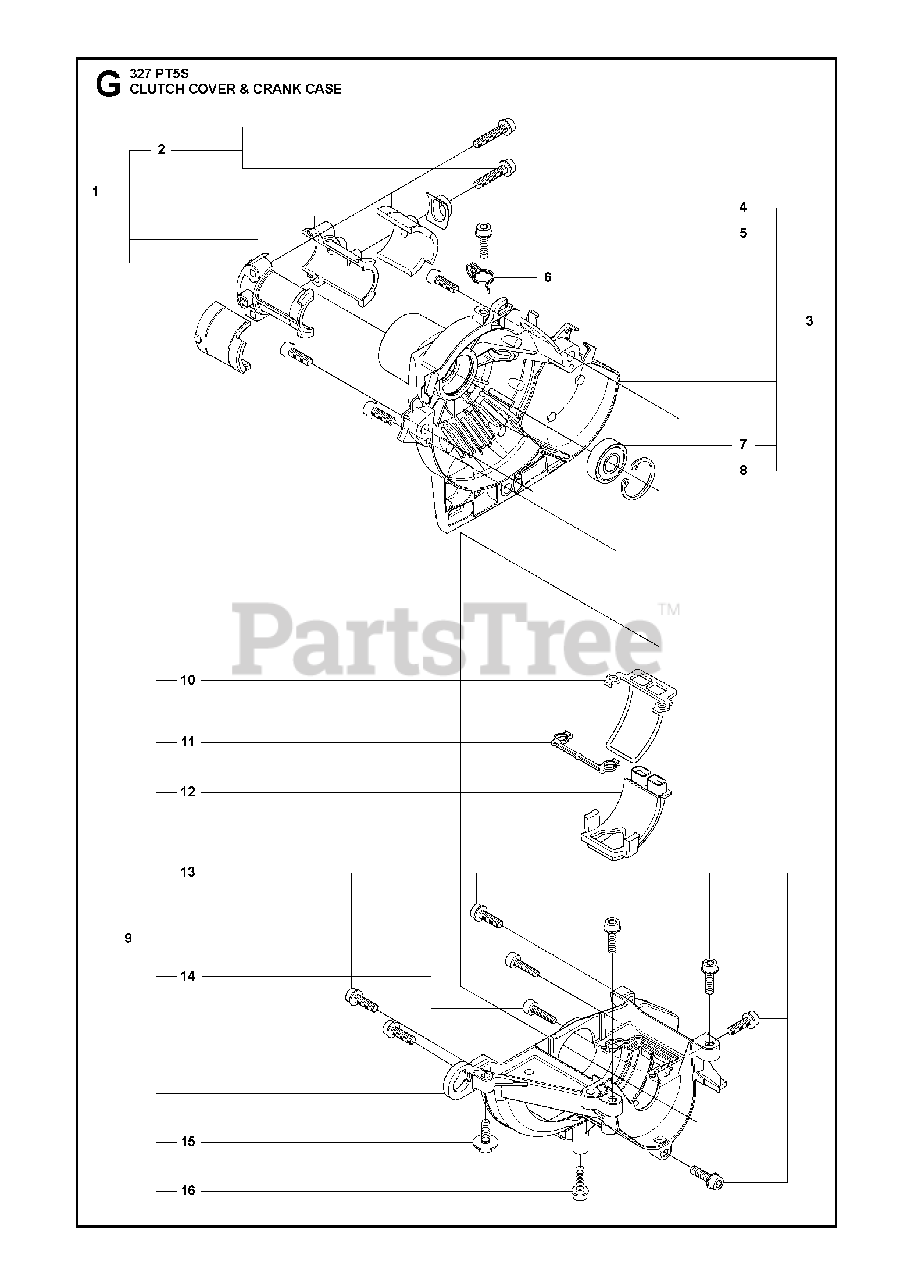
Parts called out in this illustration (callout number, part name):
1	COMPRESION SLEEVE/ISOLATOR SET
2	SCREW
3	CLUTCH COVER
4	PROTECTION PLATE
5	SCREW
6	HOLDER
7	BEARING
8	RETAINING RING
9	CRANKCASE
11	GASKET
12	CRANKCASE
13	SCREW
14	SCREW
15	SCREW
16	SCREW
